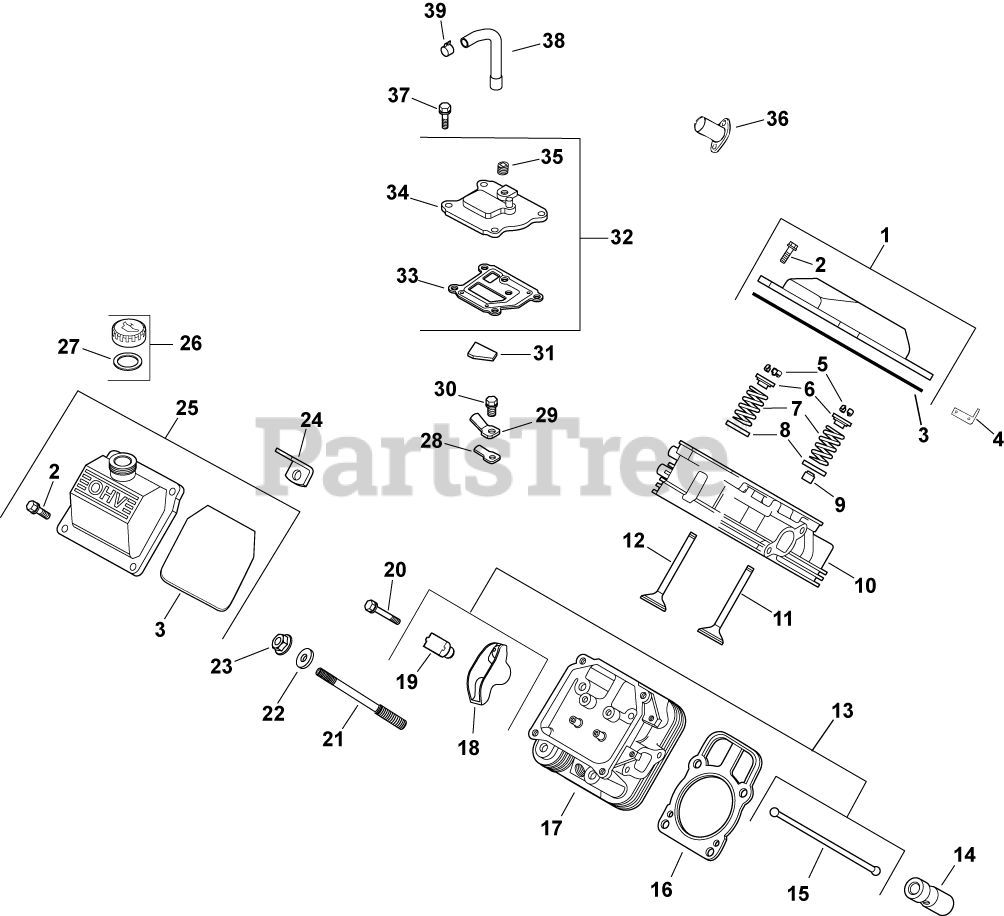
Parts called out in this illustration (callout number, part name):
1	KIT, VALVE COVER-PLAIN
2	SCREW, FLG M6X1.0X30
3	O-RING (YELLOW) -USE 24 153 30-S
4	STRAP, LIFTING-USE 25 445 03-S
5	KIT, RETAINER
6	RETAINER, VALVE SPRING - USE 25 173 28-S
7	SPRING, VALVE
8	RETAINER, SPRING
9	SEAL, VALVE STEM - (#2503214S)
10	HEAD, SERVICE ASSY CYL #1-USE 24 318 106
11	VALVE, INTAKE (STD)
12	VALVE, EXHAUST (STD) - USE 32 016 01-S
13	KIT, VALVE TRAIN
14	LIFTER, HYDRAULIC VALVE-USE 25 351 10-S
15	ROD, PUSH
16	CYL HEAD GASKET KIT-USE 24 841 04-S
17	HEAD, SERVICE ASSY CYL #2-USE 24 318 114
18	ARM, ROCKER
19	PIVOT, ROCKER ARM
20	SCREW, ROCKER ARM PIVOT-USE M-640034-S
21	STUD, M8X1.25
22	WASHER, FLAT 8.6 MM
23	NUT, FLG M8X1.25
25	KIT, VALVE COVER-OIL FILL
26	KIT, OIL FILL CAP (YELLOW)
27	O-RING, DIPSTICK
28	REED, BREATHER
29	RETAINER, REED
30	SCREW, FLG THD FRM M5X.8X10
31	FILTER, BREATHER-USE 24 050 11-S
32	KIT, BREATHER ASSEMBLY
33	GASKET, BREATHER-USE 24 041 67-S
34	COVER, BREATHER -USE 24 033 01-S
35	PLUG, CTSK PIPE 1/8"
36	LINER, EXHAUST PORT-USE 24 605 07-S
37	SCREW,FLG THD FRM M6X1.0X20-(#25086396S)
38	HOSE, BREATHER -USE 24 326 91-S
39	CLAMP, BAND SPRING HOSE-(#2523737S)
2401602-S	VALVE, EXHAUST (.25)
2401702-S	VALVE, INTAKE (.25)
